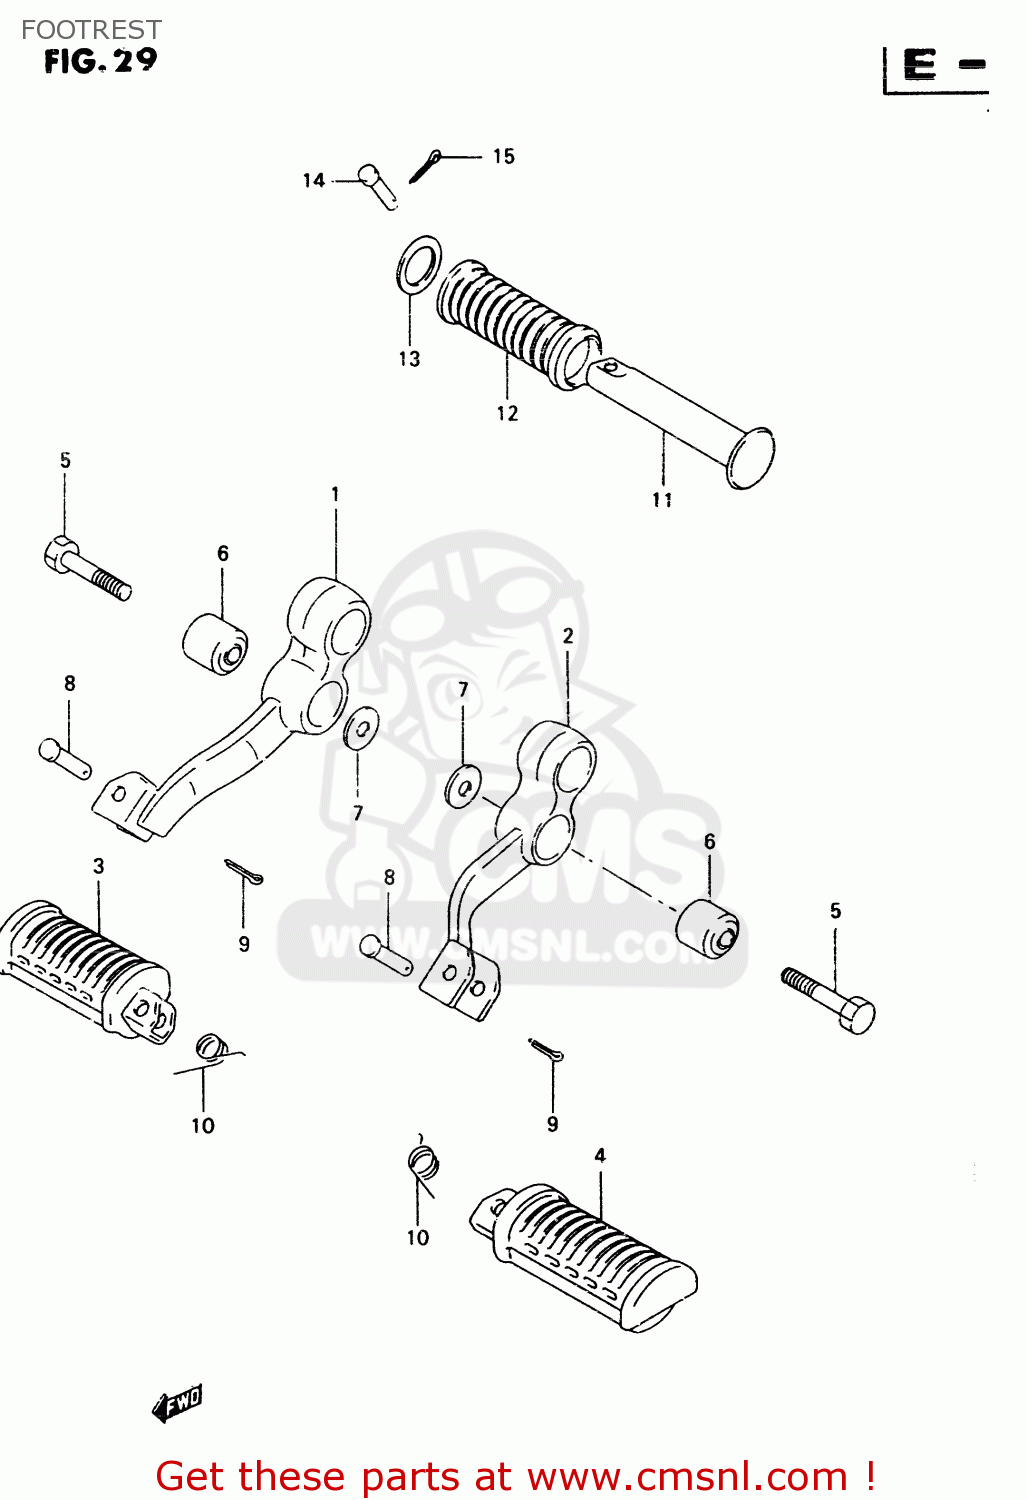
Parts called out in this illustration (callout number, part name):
1	BAR,FRONT FOOTREST,RIGHT
2	BAR,FR FOOTREST,L
3	RUBBER,PILLION FOOTREST,R
4	RUBBER,PILLION FOOTREST,L
5	BOLT(10X35)
6	BUSH
7	WASHER (10X20X2.3)
8	PIN
9	PIN 20X20
10	SPRING
11	BAR,PILLION FOOTREST
12	RUBBER,PILLION FOOTREST
13	WASHER(19.5X32X2)
14	PIN
15	PIN
